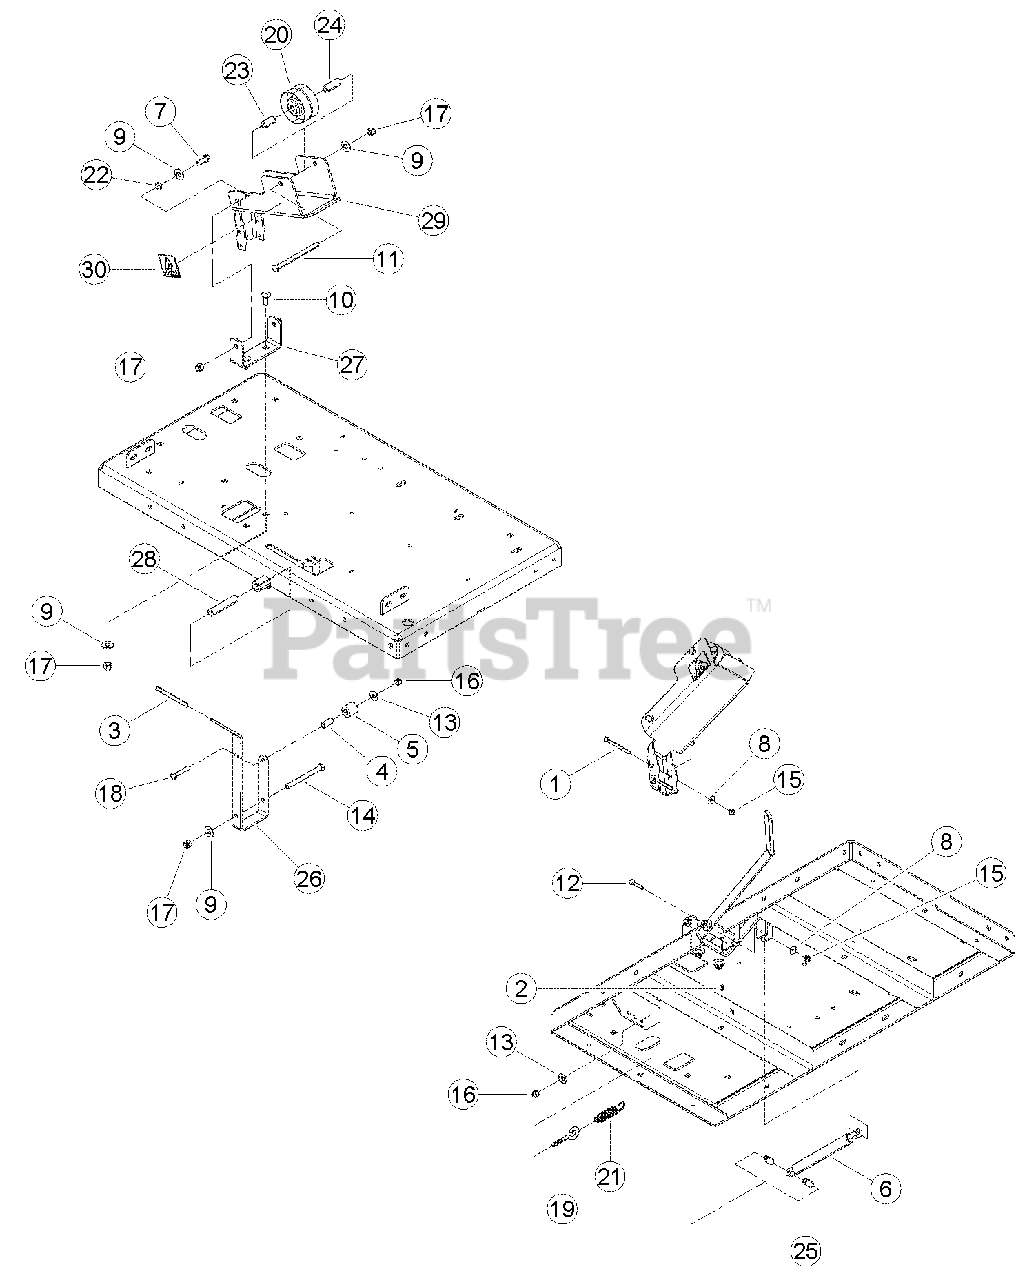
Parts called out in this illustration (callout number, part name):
1	BOLT, 1/4 X 2-3/4 HEX HD GR5 ZP
2	FITTING, 1/4 SELF-TAP GREASE
3	GRIP, CLUTCH HANDLE
4	SPACER, 0.5 X 1.00
5	ROLLER, 0.5 X 1.00 X 1.00 NYLON
6	DAMPER, IDLER
7	BOLT, 3/8 X 1 HEX HD GR5 ZP
8	WASHER, 1/4 FLAT ZP
9	WASHER, 3/8 FLAT ZP
10	BOLT, 3/8 X 1 CRG GR5 NC ZP
11	BOLT, 3/8 X 5 HEX HD GR5 ZP
12	BOLT, 1/4 X 1-1/4 HCS GR5 ZP
13	WASHER, 5/16 FLAT ZP
14	BOLT, 3/8 X 4 HHCS GR5 NC ZP
15	NUT, 1/4 NE NYLOCK ZP
16	NUT, 5/16 NE NYLOCK ZP
17	NUT, 3/8 NE NYLOCK ZP
18	BOLT, 5/16-18 X 1-3/4 HCS GR5 ZP
19	I-BOLT, 5/16-18 X 2 LONG ZP
20	PULLEY, 3-1/4 FLAT IDLER
21	SPRING, 3/4" OD EXTENSION
22	SPACER, IDLER PIVOT
23	SPACER, IDLER
24	SPACER .63 X 1.63
25	SPACER, .50 X .775
26	LEVER, CHIPPER ENGAGEMENT
27	ANCHOR, IDLER
28	SPACER, .63 X 3.060
29	ASSEMBLY, IDLER BRACKET, SERVICE PART
30	DECAL, SHIELD DANGER ISO
